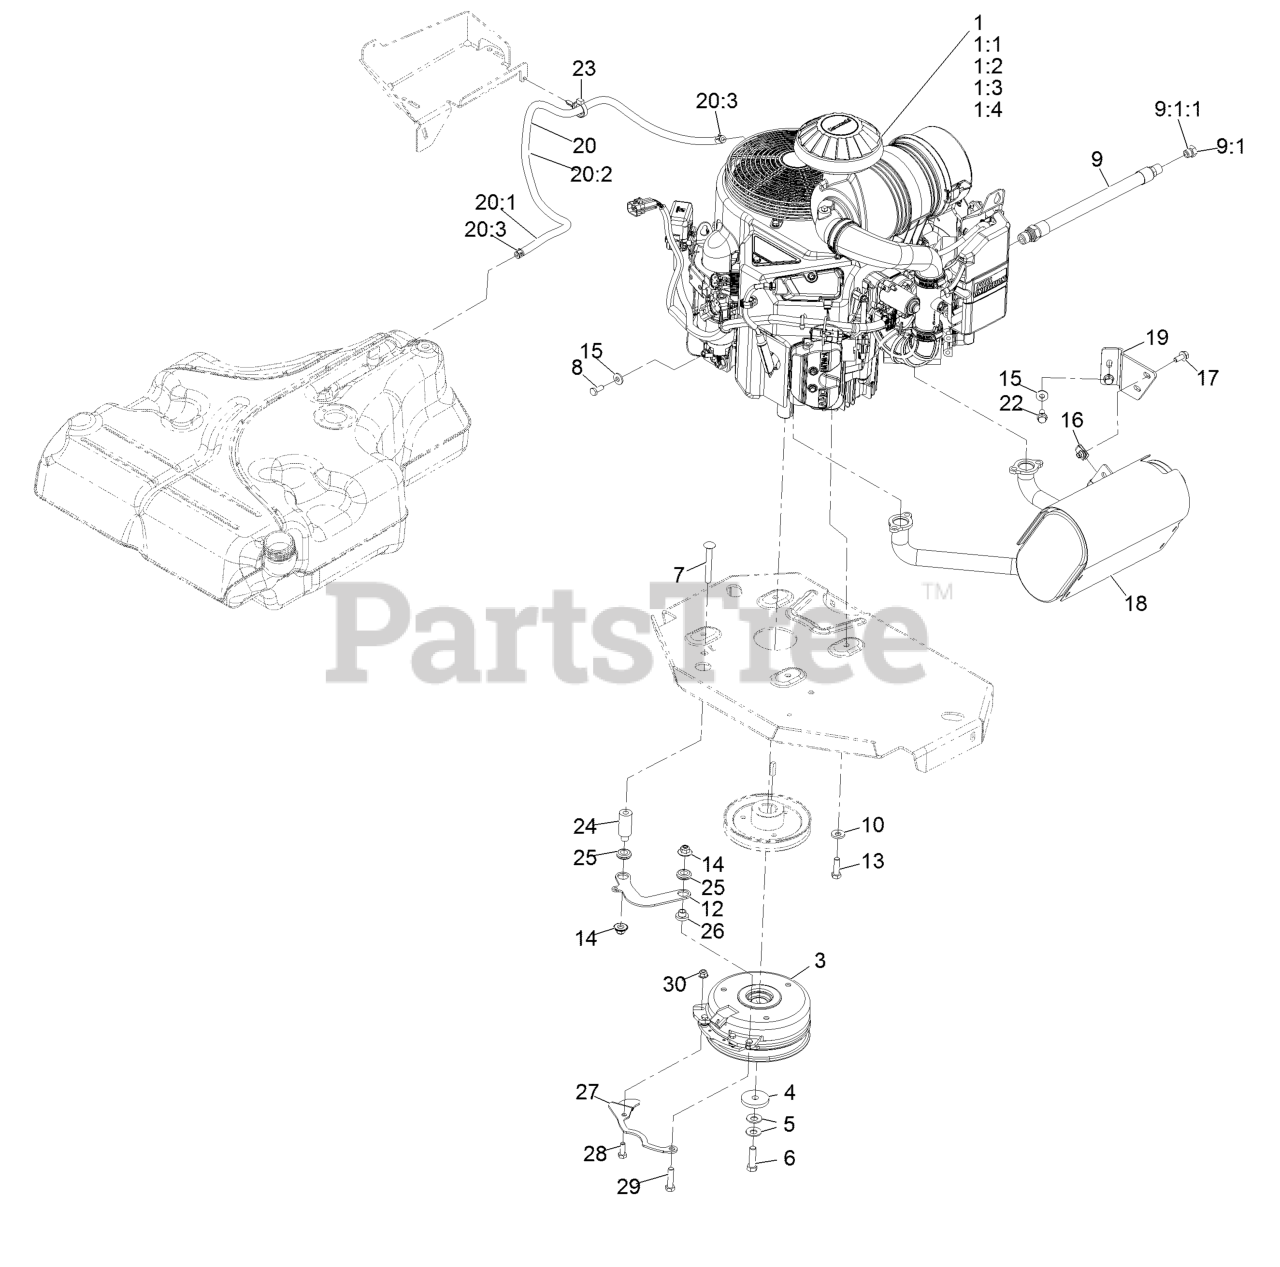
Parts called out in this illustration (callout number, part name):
1:1	Kawasaki 49065-2078 Engine Oil Filter
1:2	Kawasaki 49019-0031 Fuel Filter
1:3	Kawasaki 11013-7039 Safety Filter
1:4	Kawasaki 11013-7038 Air Filter
3	Clutch Kit
4	Washer-Clutch
5	Washer-Spring Disc 7/16
6	Screw-HH 7/16-20 X 1 1/2 W/Loctite
7	Bolt-Carriage 3/8-16 X 3
8	Screw-HH M8-1.25 X 20Mm
9	Asm-Hose Oil Drain W/Plug
9:1	Plug-W/O-Ring
9:1:1	O-Ring
10	Washer-Spring Disc 3/8
12	Link-Anchor, Clutch
13	Screw-HH 3/8-16 X 1 1/4
14	Nut-Nyloc 3/8-16 Flg
15	Washer-Spring Disc 5/16
17	Screw-HH Flg 5/16-18 X 3/4
18	Muffler
19	Bracket-Muffler
20	Fuel Line ASM
20:1	Hose-Fuel Line 38 1/4"
20:2	Sleeve-Thermal
20:3	Clamp-Hose
22	Screw-HH M8-1.25 X 20Mm
23	Clamp-Hose
25	Grommet-Rubber
27	Belt-Guide
28	Screw-HH 5/16-18 X 7/8
29	Screw-HH 3/8-16 X 1 1/2
30	Nut-Nyloc 5/16-18 Flg
